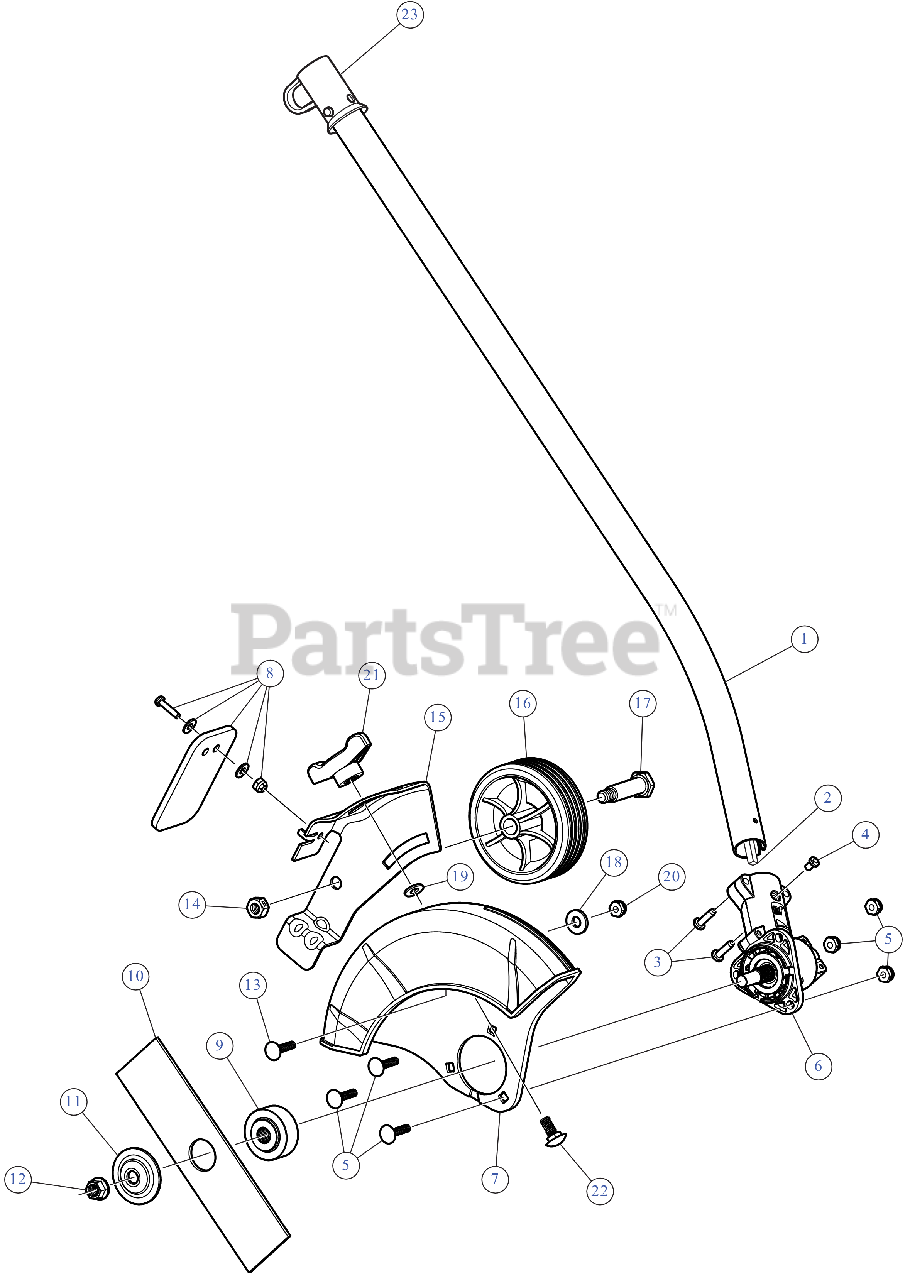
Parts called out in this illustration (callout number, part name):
1	BOOM ASSEMBLY LE
2	LOWER DRIVE SHAFT
4	SCREW, 8-32 x .312 P
5	HDWR ASM:GUARD MT
6	GRBX ASSEMBLY
8	DEFLECTOR W/HDW
10	EDGER BLADE
11	WASHER-BLADE CLAMP BRUSH CUT
12	BLADE LOCK NUT
13	BOLT:WHEEL MT BRACKET
14	LOCK NUT 3/8-16
15	BRACKET GUARD
16	WHEEL 3.75" (WHITE)
17	BOLT
18	WASH, FLAT .734 OD
19	WASHER .406X1.0X.095
20	NYLON LOCK NUT
21	WING KNOB 5/16-18
22	CARRIAGE BOLT 5/16-18 x .75
